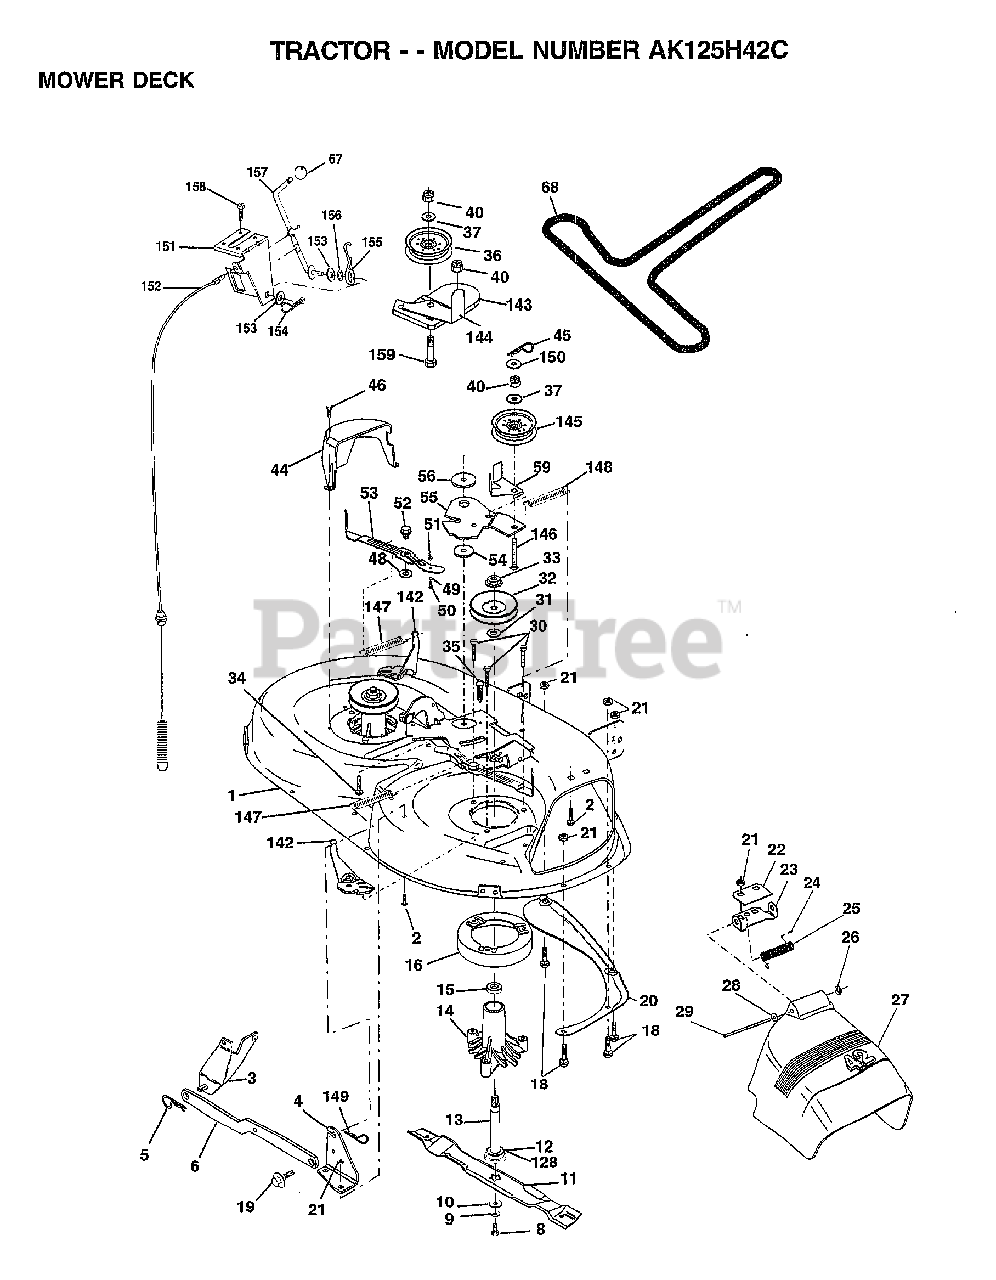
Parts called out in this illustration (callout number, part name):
1	MOWER DECK ASSY
2	BOLT
3	BRKT ASM SWAY BAR
4	BRACKET DECK
8	BLADE BOLT
10	WASHER.HARD.BLADE
11	"BLADE.42"" HIPERF"
12	BEARING.BALL
14	HSG ASM MANDREL
15	BEARING
16	STRIPPER RND MWR
18	BOLT
19	BOLT SHD 5/16-18
20	BAFFLE VORTEX 42
22	STIFFENER BRKT
23	DEFLECTOR BRKT
24	CAP-SLEEVE LT
25	SPRING TORSION
26	NUT PUSH M
27	SHIELD DEFLECTOR 42''
28	WASHER
29	HINGE ROD
30	"SCREW-THD ROLL,WA"
31	WASHER
32	PULLEY.MANDREL.42
34	BOLT
35	XMAS TREE FASTNER
36	FLAT IDLER PULLEY
37	WASHER
44	GUARD MAND LH BLK
45	RETAINER M
46	SCREW.1/4-20X5/8
48	HARD SMALL WASHER
49	ROLLER ASM-CAM
50	SHOULDER BOLT
51	LOCKNUT
52	BOLT.SHLD.5/16-18
53	BRAKE PAD ARM ASM
54	HARDENED WASHER
55	ARM-IDLER
56	SPACER.RETAINER.MOWER
59	GUARD IDLER TUV
67	KNOB T(3/8 HOLE)
68	BELT-V.SEC.46.KEL
128	WASHER.FELT.
142	ARM SPRING BRAKE MOWER
143	BRACKET ARM IDLER
144	KEEPER BELT CLUTCH CABLE
145	PULLEY IDLER FLAT
146	BOLT
147	SPRING EXTENSION
148	SPRING RETURN IDLER
149	RETAINER SPRING
150	WASHER PM
151	BRKT CLUTCH CABLE
152	"CABLE.CLUTCH.42"""
153	WASHER FLAT
154	SPRING RETAINER
155	SPRING RETENTION LVR CLUTCH CAB
156	SPACER
157	ROD.CLUTCH.CABLE.3/8
158	SCREW LT
159	BOLT
